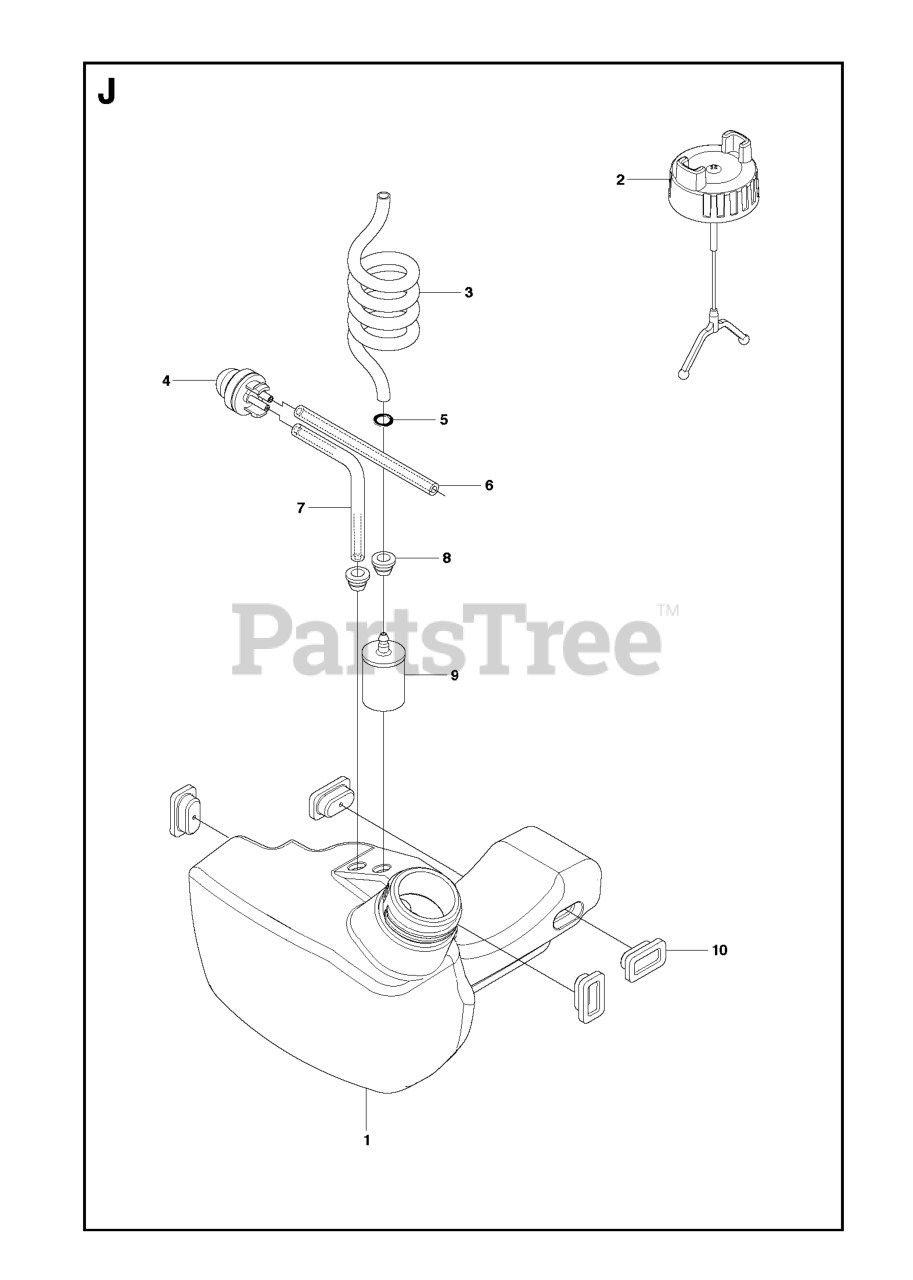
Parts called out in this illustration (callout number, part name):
2	%FUEL CAP
3	FUEL HOSE
4	AIR PURGE BUBBLE
8	FUEL TANK BUSHING
9	RP FUEL FILTER
